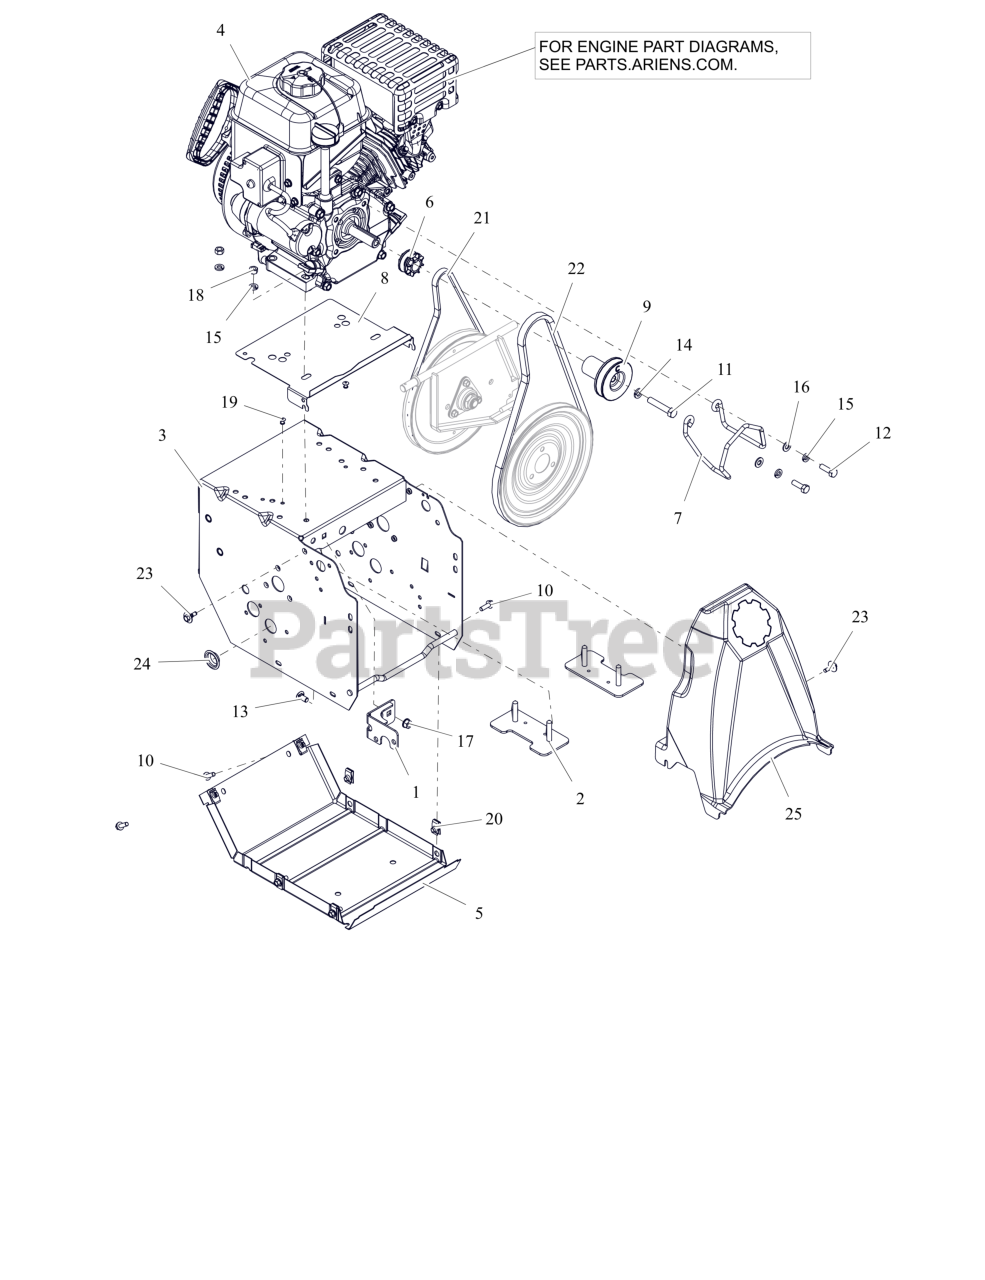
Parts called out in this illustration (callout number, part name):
1	WELDMENT, FRAME BRACKET
2	STRAP, ENGINE BOLT-WELDMENT
3	FRAME, MAIN
4	ENGINE, AX223 GEN 2 120V/60W
5	COVER, BOTTOM
6	SHEAVE, TRACTION
7	FINGER, BELT
8	BAFFLE, COMPACT
9	SHEAVE, ATTACHMENT SINGLE GRV
10	BLT, HWH .25-20X.75 G5 ZCC
11	BLT, HEX .38-24X2.00 G5 ZCC
12	BLT, HEX 0.3125-24X1 G5 ZCC
13	BLT, RHSSN .31-18X.625 G5 ZCC
14	WSHR,LK-REG .375X.094 ZCC
15	WSHR, LK-HVY .312X.097 ZCC
16	WSHR,FLT .344X.688X.065 ZCC
17	NUT-LK-TOP-FLG .312-18 GF ZCC
18	NUT, HEX .312-18 ZCC
19	RVT, POP .1875 ZCC
20	NUT-RTNR .25-20X.56
21	V-BELT, 3L-WRAPPED
22	V-BELT, HA-RAW EDGE
23	SCR-TAP .25-20X.5 CAPTIVE
24	PLUG, HOLE - 1.00" FLEXTEMP
25	COVER- CLASSIC BELT
